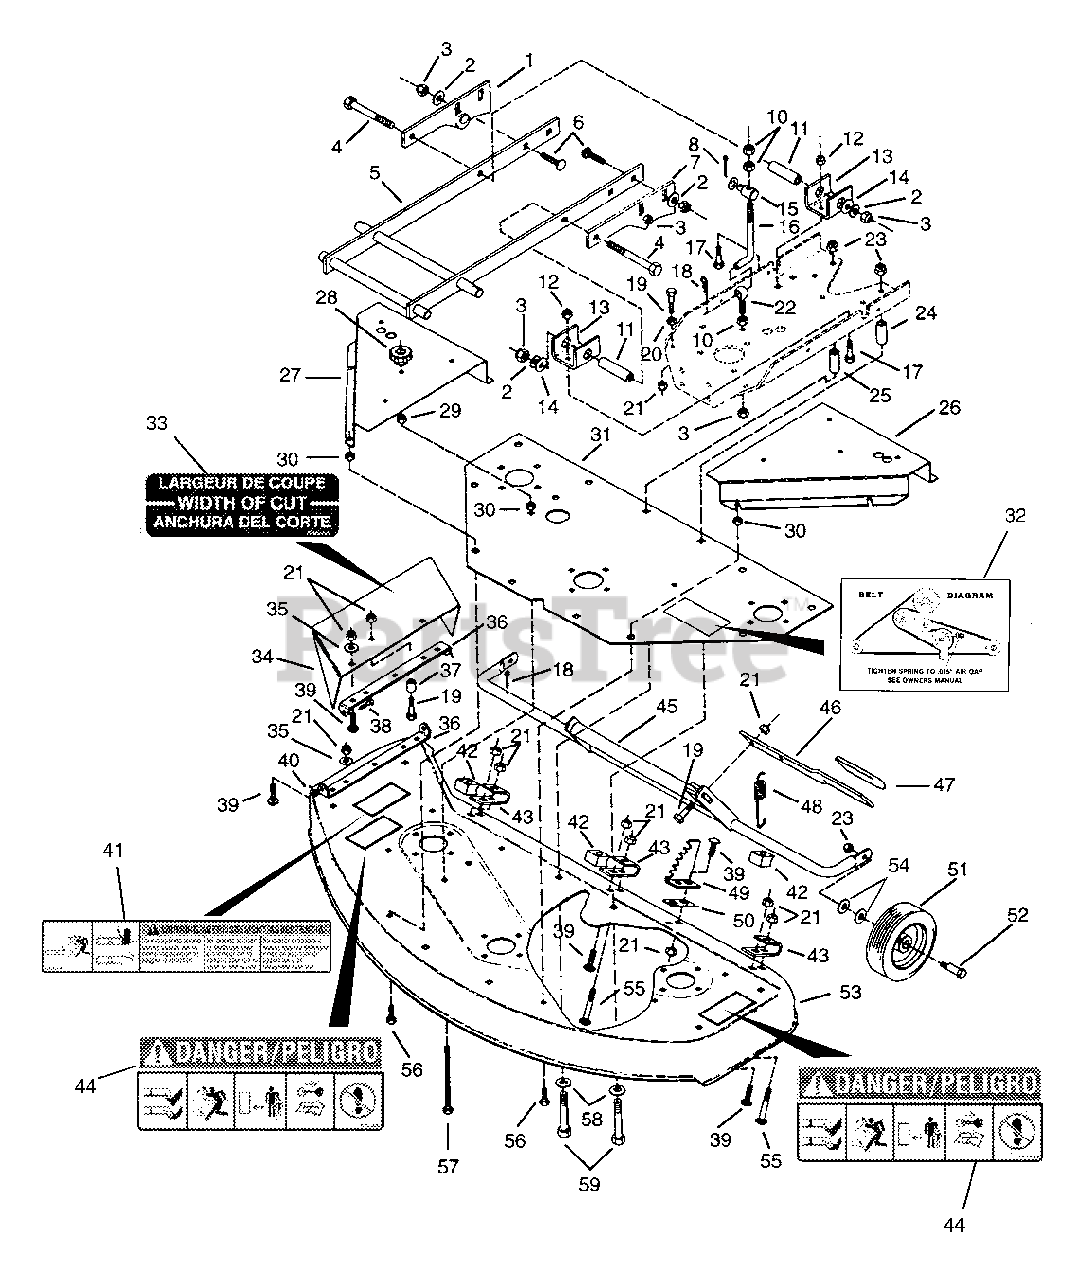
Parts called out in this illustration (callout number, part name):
1	Weldment, Deck Leveling Right Hand
2	Washer-Flat-Steel .531 x 1.250 x .100
3	Nut-Locking-Center .50-13
4	Bolt-Hex .50-13X3.25 Grade 5
5	Weldment, Pivot Arm
6	Bolt-Round Head Square Neck .50-13 x 1.25 Grade 5
7	Weldment, Deck Leveling Left Hand
8	Pin-Cotter .12 x 1.25
9	Washer-Flat-Steel .531 x 1.000 x .063
10	Nut-Jam .50-13
11	Spacer .510 x .750 x 2.02 Steel
12	Nut-Locking-Center .31-18
13	Support, Mower Pivot
14	Washer-Flat-Steel .813 x 1.370 x .100
15	Pivot, Mower Lift
16	Rod, Lift
17	Bolt-Hex .31-18X.875 Grade 5
18	Pin-Cotter .12 x 2.0
19	Bolt-Hex .38-16 x 1.50 Grade 5
20	Nut-Jam .375-16
21	Nut-Locking-Nylon .38-16
22	Bolt-Eye .56 x 2.12
23	Nut-Locking-Nylon .50-13
24	Spacer .510 x .840 x 2.437 Steel
25	Spacer .560 x .750 x 2.437 Steel
26	Cover, Belt Left Hand
27	Cover, Belt Right Hand
28	Knob
29	Nut-Locking-Nylon .312-18
30	Nut-Jam .312-18
31	Plate, Support
32	Decal, Belt Installation
33	Width of Cut Decal
34	Chute, 40" Flip-Up
35	Washer-Flat-Steel .406 x .812 x .065
36	Bracket, Chute 40" Mower
37	Bushing-Sleeve .407 x .625 x .750
38	Bolt-Hex .25-20 x .875
39	Bolt-Round Head Square Neck .38-16X1.00
40	Nut-Locking-Nylon .250-20
41	Decal, Mower Pan Danger
42	Stop, Nylon
43	Bracket, Axle Support
44	Decal, Warning
45	Weldment, Axle Pivot
46	Lever, Height of Cut
47	Grip, Handle
48	Spring-Tension .095 x .85 x 4.38
49	Bracket, Height Adjustment
50	Shim, Mower Height Adjuster Bracket
51	Tire/Wheel Assembly 6 x 2
52	Bolt, Eccentric
53	Weldment, 40" Mower Deck
54	Washer-Flat-STL .511 x 1.44 x .125
55	Bolt-Round Head Square Neck .38-16 x 2.00 Grade 5
56	Bolt-Hex .31-18X.75 Grade 5
57	Bolt-Round Head Square Neck .31-18 x 3.50 Grade 5
58	Washer-Flat-Steel .531 x 1.06 x .095
59	Bolt-Hex .50-13 x 3.75 Grade 5
